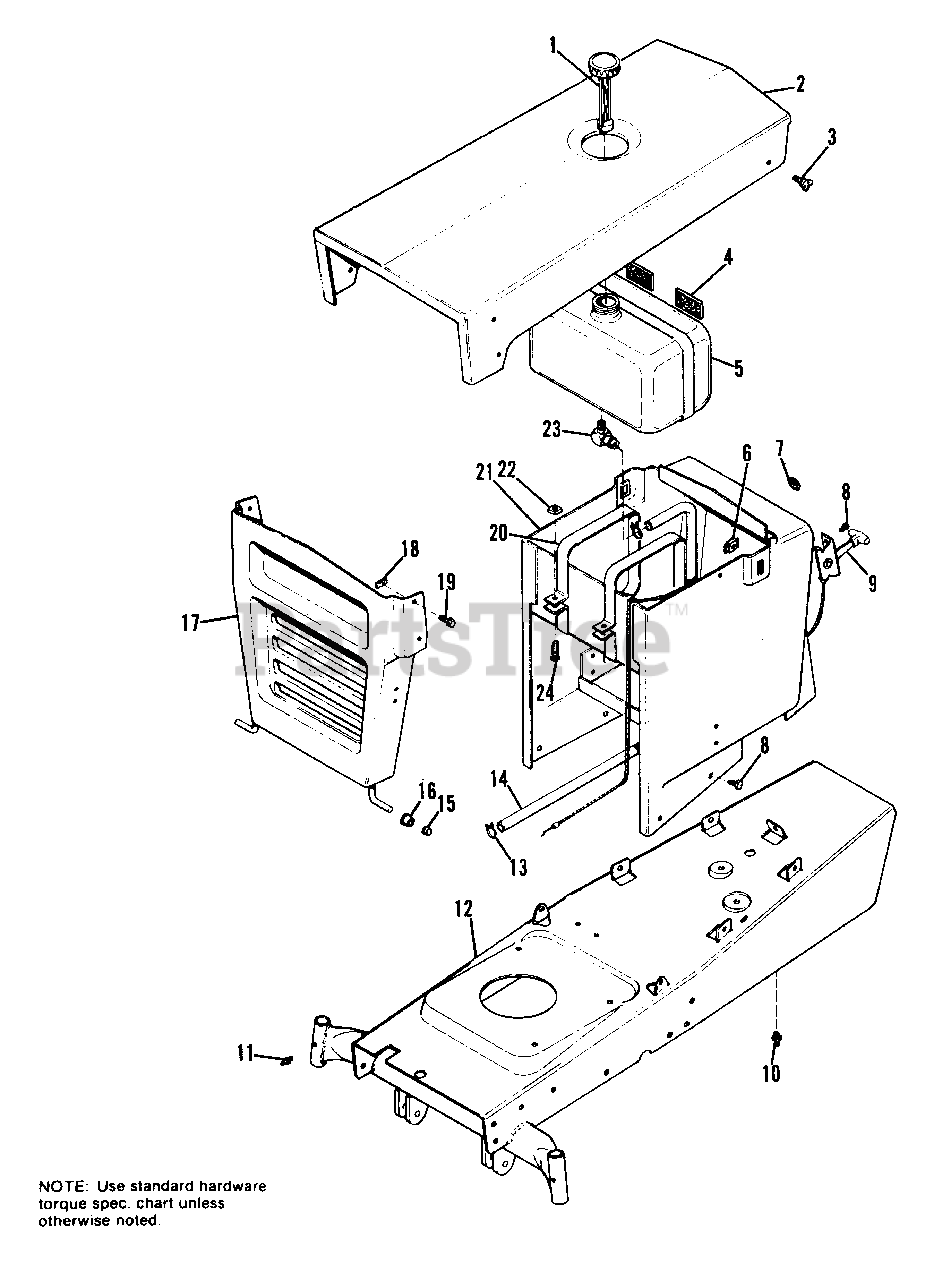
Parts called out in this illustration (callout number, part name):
1	CAP, Fuel Tank
3	SCREW, Thumb
4	GASKET, Felt
5	TANK, Fuel
6	NUT, Retainer
7	BUTTON, Plug
8	SCREW, Hex, Taptite, 1/4-20 x 3/8
9	CONTROL, Throttle
10	FITTING, Grease
11	FlTTING, Grease
12	FRAME ASSY.
13	CLAMP, Hose
15	PUSHNUT
17	GRILLE ASSY.
19	SCREW, Hex, Flange, 1/4-20 x 3/4
20	STRAP, Tank
21	DASH ASSY.
22	NUT, Square, 1/4-20
23	FITTING, Elbow, 90ø
24	SCREW, Machine, 1/4-20 x 1-1/2
